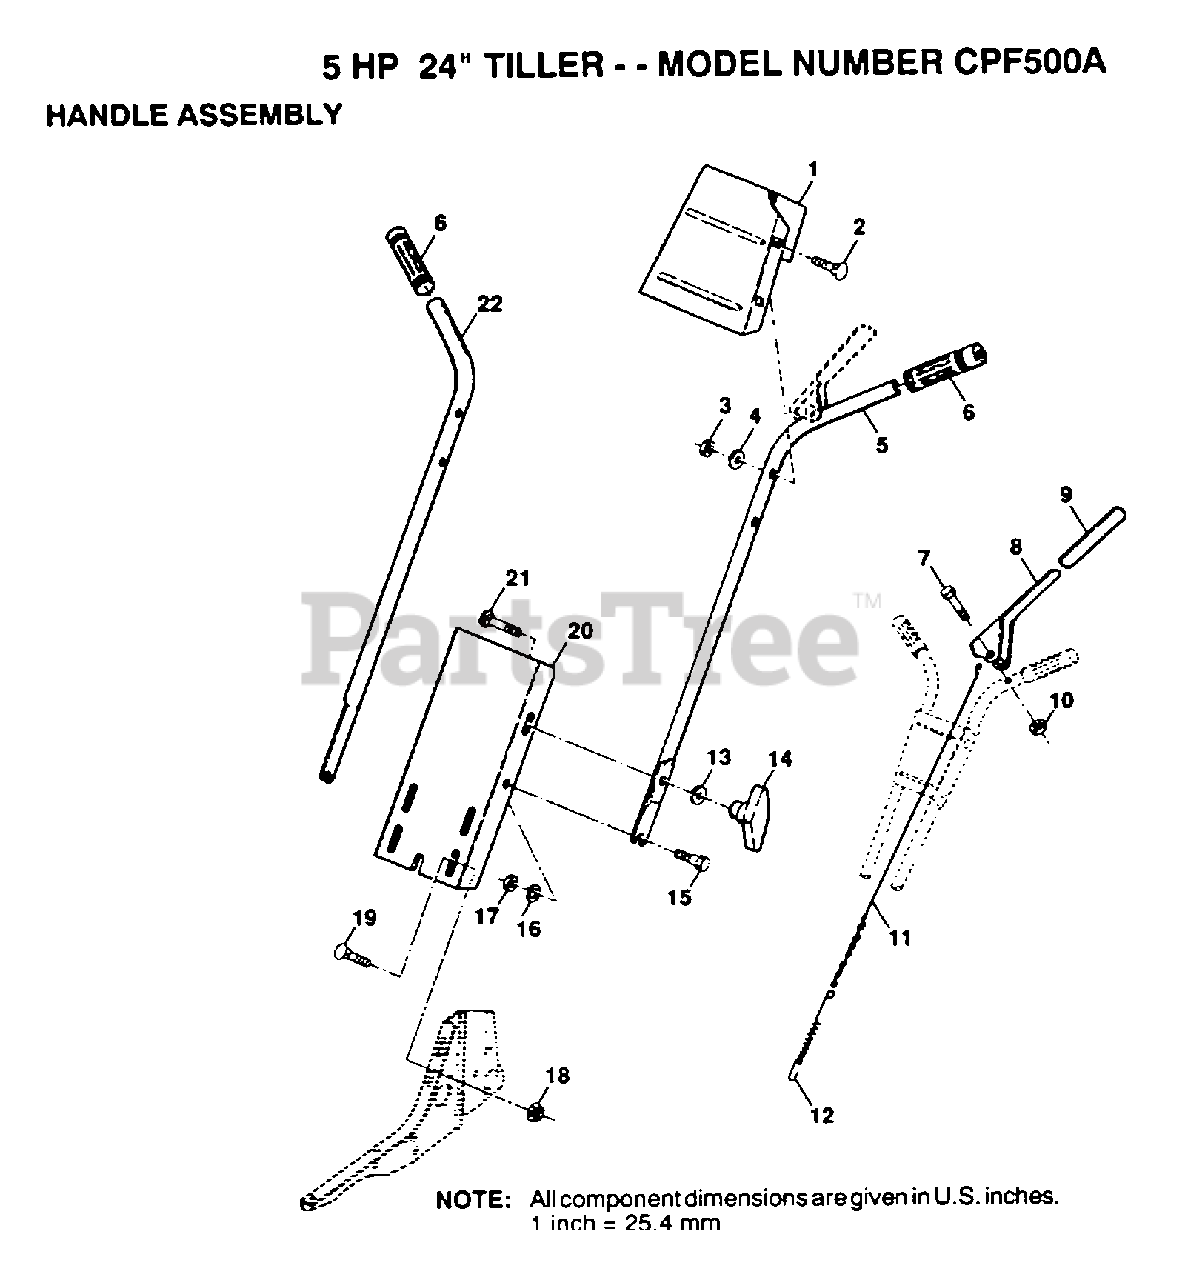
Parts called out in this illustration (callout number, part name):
1	"BRKT,HANDLE "
2	BOLT
4	WASHER
7	BOLT.HEX.5/16-1.5
9	GRIP T
12	SPRING EXT TI
13	WASHER
16	LOCKWASHER
17	NUT.HEX.5/16-18
18	NUT
19	BOLT
21	BOLT
